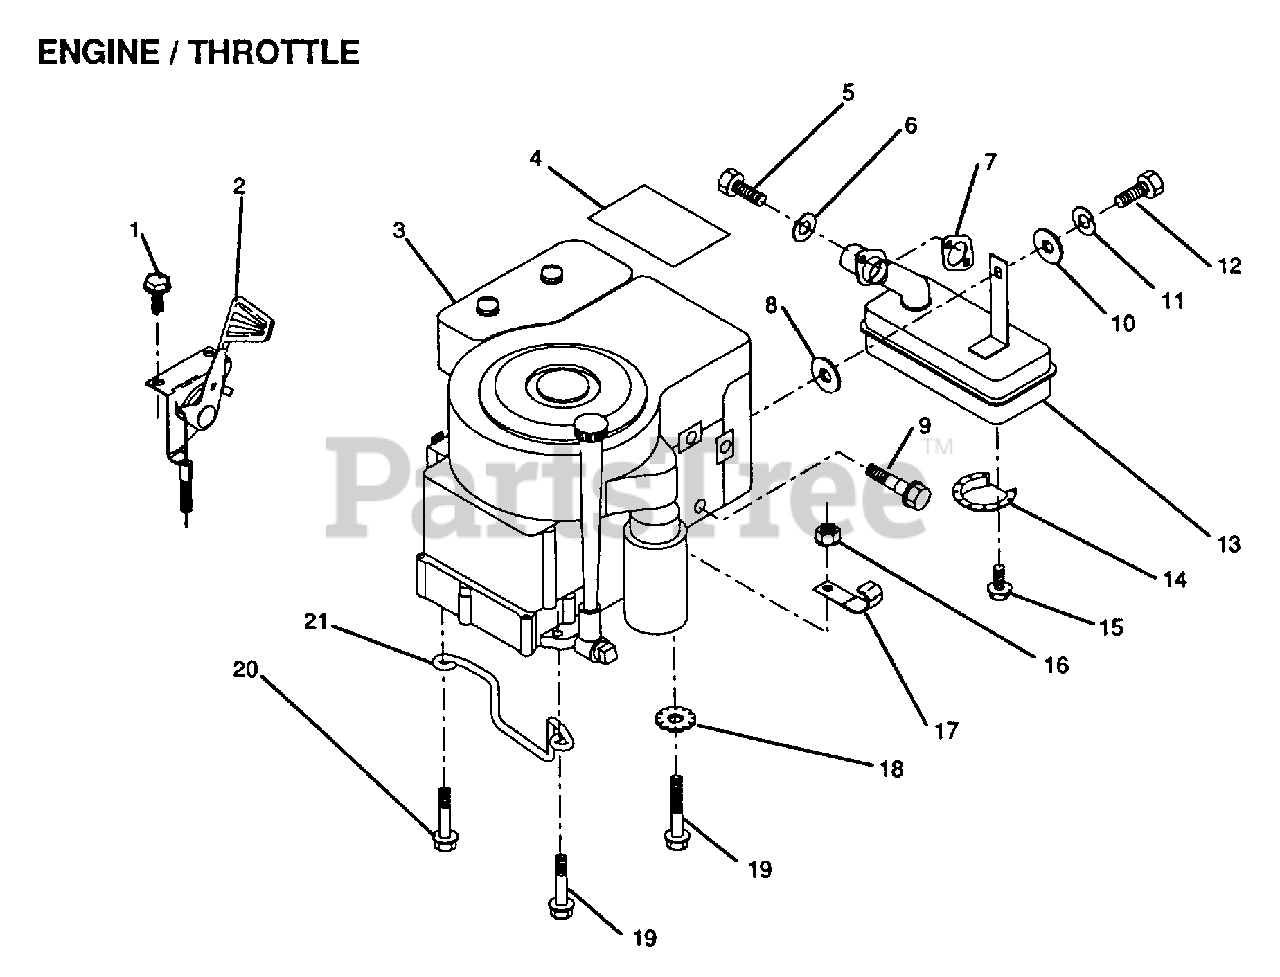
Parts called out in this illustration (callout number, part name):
1	SCREW
3	ENGINE BRIGGS AND STRATTON
4	DECAL.ENG.27164
5	SCREW
6	LOCKWASHER
8	SPACER T
9	BOLT T
11	LOCKWASHER
14	DEFLECTOR.222573
16	NUT
17	CLIP T
18	LOCKWASHER
19	SCREW LT
20	SCREW LT
